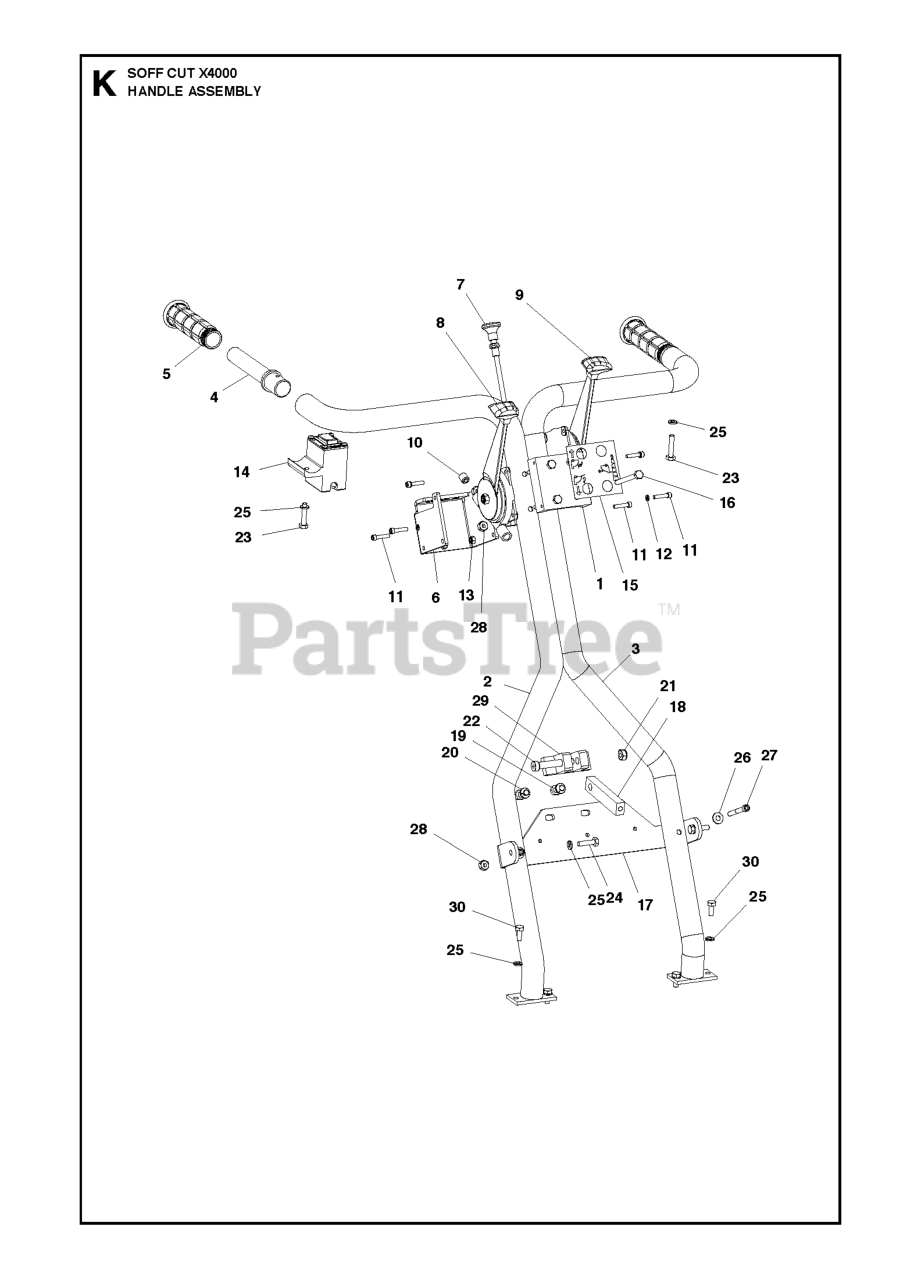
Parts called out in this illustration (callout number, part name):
19	SCREW
21	NUT
28	NUT
